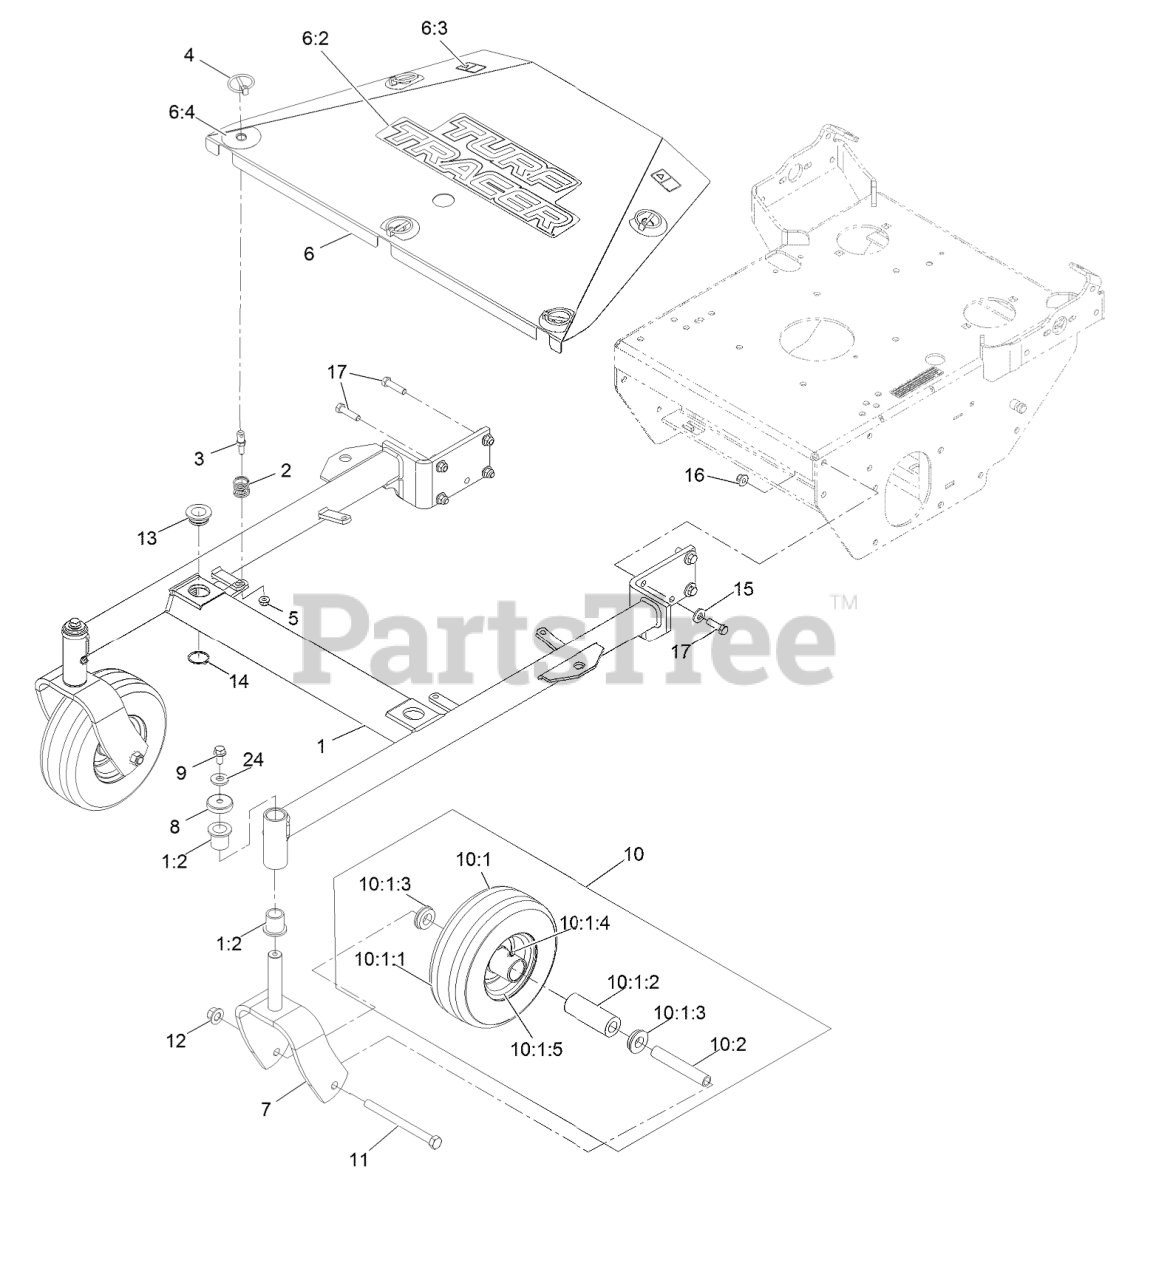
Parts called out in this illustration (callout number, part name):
1	ASM, FRAME W/ BUSHINGS, 3
1:2	BEARING-FLANGED
3	PIN-SPRING
4	PIN-LYNCH
5	NUT-HF, NI
6	ASM, SHIELD W/ DECALS, 36
6:2	DECAL-TURF TRACER
6:3	DECAL-WARNING
6:4	DECAL-SCRATCH COVER
7	FORK, CASTER
8	CAP, DUST
9	SCREW-HHF
10	KIT, SP CASTER WHEEL REPL
10:1	Wheel And Tire ASM
10:1:1	Tire
10:1:2	BEARING
10:1:3	BUSHING
10:1:4	FITTING-GREASE
10:1:5	Wheel
11	SCREW-HH
12	Nut-Lock 1/2-13
13	BUSHING-DECK
14	RING-RETAINING
15	WASHER-BELLEVILLE
16	NUT-HF, NI
17	SCREW-HH
